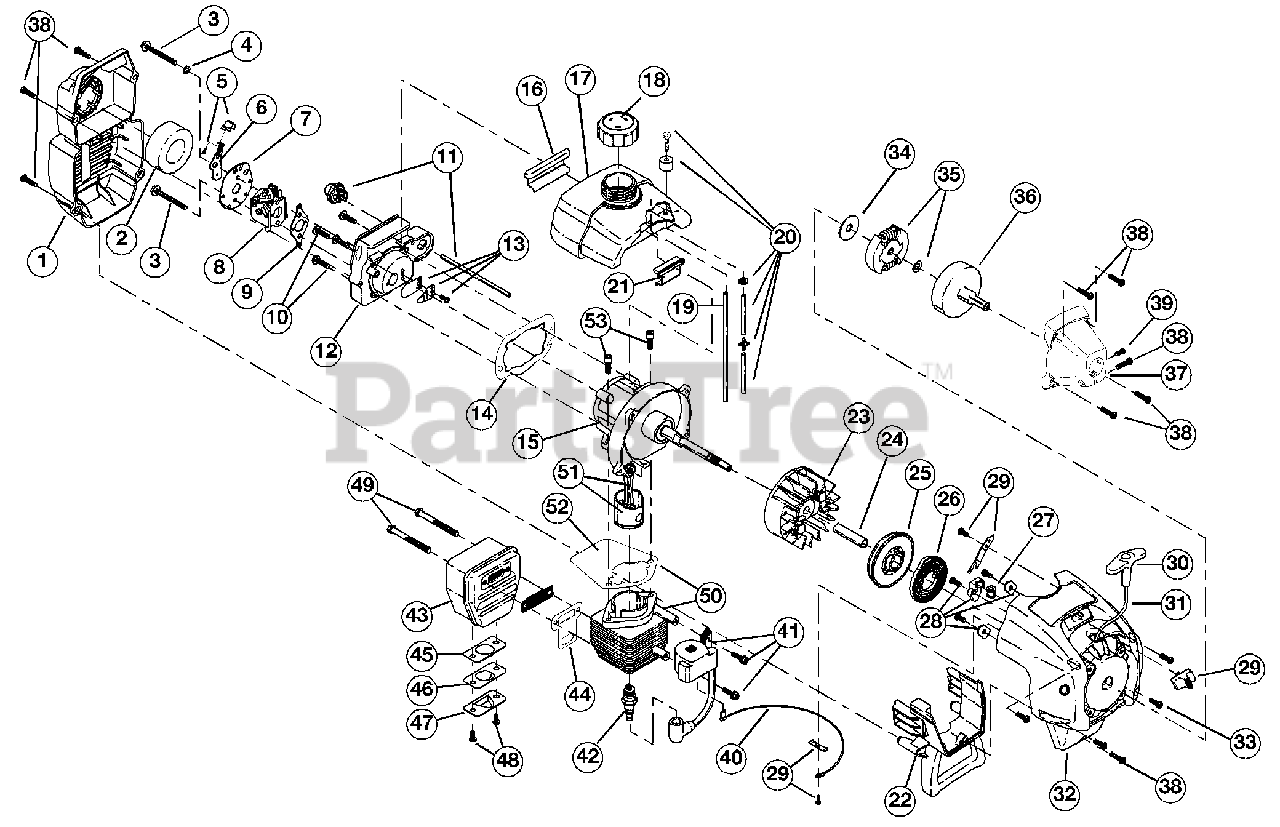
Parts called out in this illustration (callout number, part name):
1	Air Cleaner Assembly
2	Air Cleaner Filter
3	Carburetor Mounting Screw
4	Wavey Washer
5	Choke Knob and Screw
6	Choke Lever Assembly
7	Choke Plate Assembly
8	Carburetor Assembly
9	Carburetor Gasket
10	Carb Mount Screw
11	Primer and Hose Assembly
12	Carb Mount Assembly
13	Reed Assembly
14	Carburetor Mount Gasket
15	Crank Case Service Assembly
16	Rear Mounting Pad
17	Fuel Tank Assembly
18	Fuel Cap
19	Fuel Return Line
20	Fuel Line Assembly
21	Front Mounting Pad
22	Shroud Extension and Stand
23	Flywheel
25	Recoil Pulley
26	Recoil Spring
27	Rope Guide
28	Pulley Retainer Assembly
29	Switch Assembly
30	Pull Handle
32	Starter Housing Assembly
33	Housing Screw
34	Clutch Washer
35	Clutch Rotor Assembly
36	Clutch Drum
37	Clutch Cover Assembly
39	Anti-Rotation Screw
40	Wire Lead
41	Module Assembly
42	Spark Plug
43	Muffler Assembly
44	Exhaust Gasket
45	Spark Arrestor Screen
46	Exhaust Hood Diverter
47	Exhaust Hood
48	Screws
49	Muffler Mounting Bolt Assembly
50	Cylinder Assembly
51	Piston and Rod Assembly
52	Cylinder Gasket
53	Cylinder Bolt
